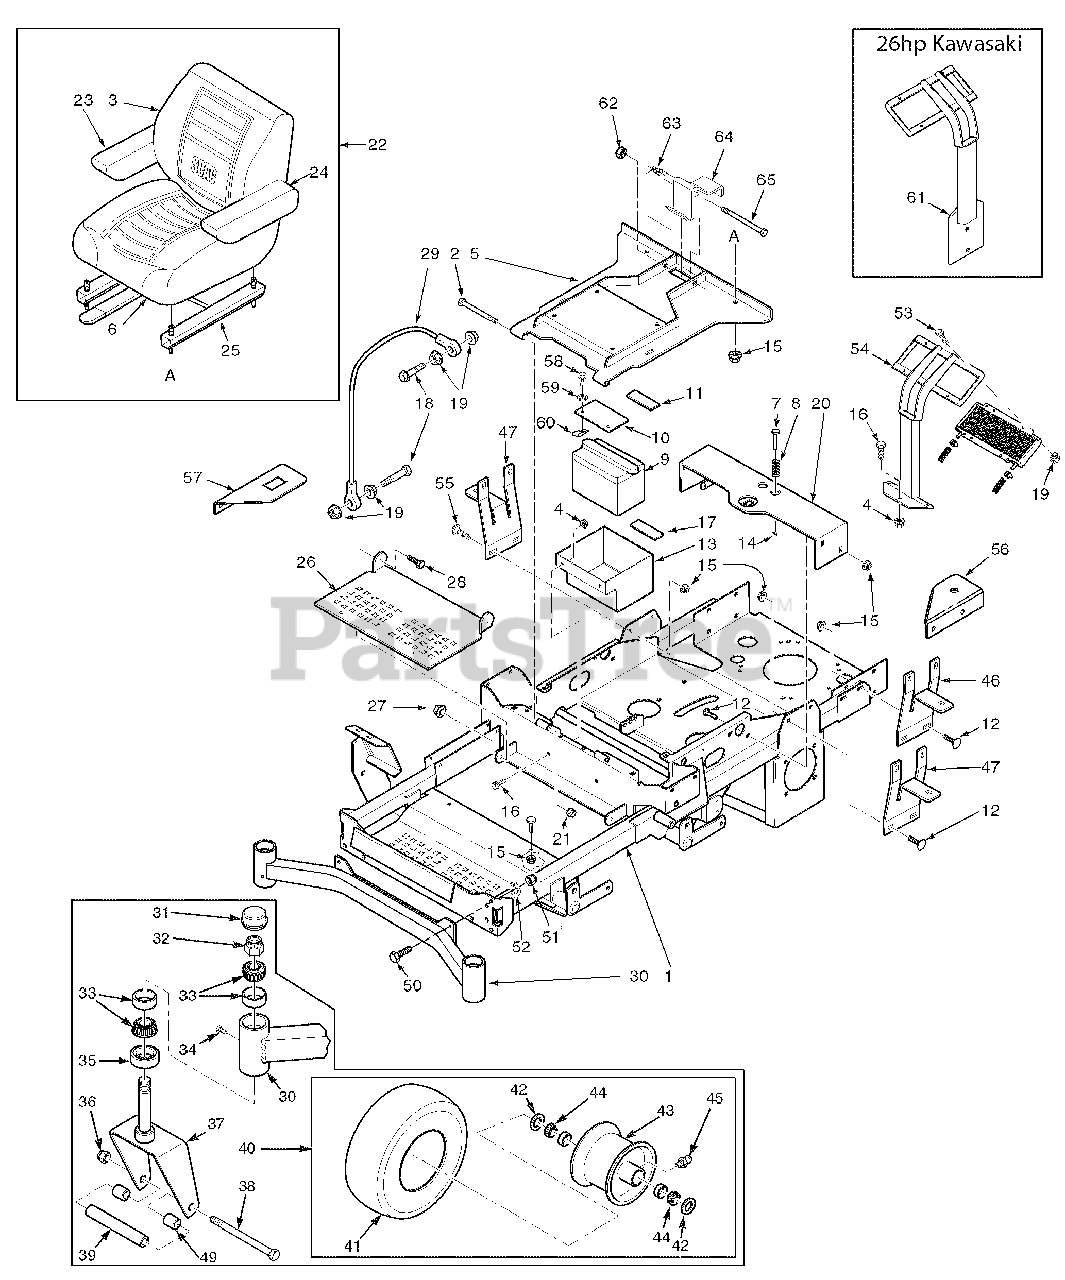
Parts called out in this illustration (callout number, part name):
1	Main Frame Assembly w/decals
2	Bolt, Hex Head 5/16-18 x 3-3/4"
3	Back Cover
4	Nut, Serr. Flange 3/8-16
5	Plate, Seat Mounting
6	Cushion Cover
7	Pin Retainer, Spring
8	Spring
9	Battery
10	Battery Cover
11	Battery Hold Down Pad
12	Bolt, Carr. 5/16-18 x 3/4"
13	Battery Box
14	Roll Pin, Spring 5/32 x 3/4"
15	Nut, Serr. Flange 5/16-18
16	Bolt, Hex Head 3/8-16 x 1"
17	Pad, Rubber
18	Bolt, Hex Head 1/4-20 x 1-1/4"
19	Nut, Serr. Flange 1/4-20
20	Seat Base Support
21	Nut, Elastic Stop 5/16-18
22	Seat Assembly w/ adj. rails and seat belt
23	Armrest Cover
24	Armrest Cover
25	Seat Track Set
26	Footplate
27	Nut, Elastic Stop 3/8-16
28	Bolt, Hex Head 3/8-16 x 1"
29	Cable, Seat Stop
30	Weldment, Caster Support
31	Cap, Grease
32	Nut, Elastic Stop 1.0-14
33	Bearing Set
34	Plug, 1/4-28
35	Seal, 2.0" OD x 1.625" ID
36	Nut, Elastic Stop 1/2-13
37	Yoke, Front Caster Wheel
38	Bolt, Hex Head 1/2-13 x 9-1/2"
39	Sleeve
40	Caster Wheel Assembly
41	Tire, 13 x 6.5 Smooth
43	Rim
44	Roller Bearing
45	Fitting, Grease
46	Mounting Bracket, Oil Tank
47	Mounting Bracket, Fuel Tank
48	Seat Pan
49	Spacer, Caster Wheel
50	Bolt, Hex Head 7/16-14 x 1-1/4"
51	Nut, Elastic Stop 7/16-14
52	Lockwasher, 7/16"
53	Bolt, Hex Head 1/4-20 x 5/8"
54	Support Weldment, Oil Cooler
55	Bolt, Carriage 5/16-18 x 1"
56	Bracket, Fuel Valve
57	Bracket, Hour Meter
58	Bolt, Hex Head 3/8-16 x 1-1/4"
59	Lock Washer. 3/8" Spring
60	U-Nut, 3/8-16
61	Support Weld, Oil Cooler - 26hp Kaw.
62	Lock Nut, 3/8-16 Center Lock
63	Spring, Seat Latch
64	Seat Latch Weldment
65	Bolt, Hex Head 3/8-16 x 6"
